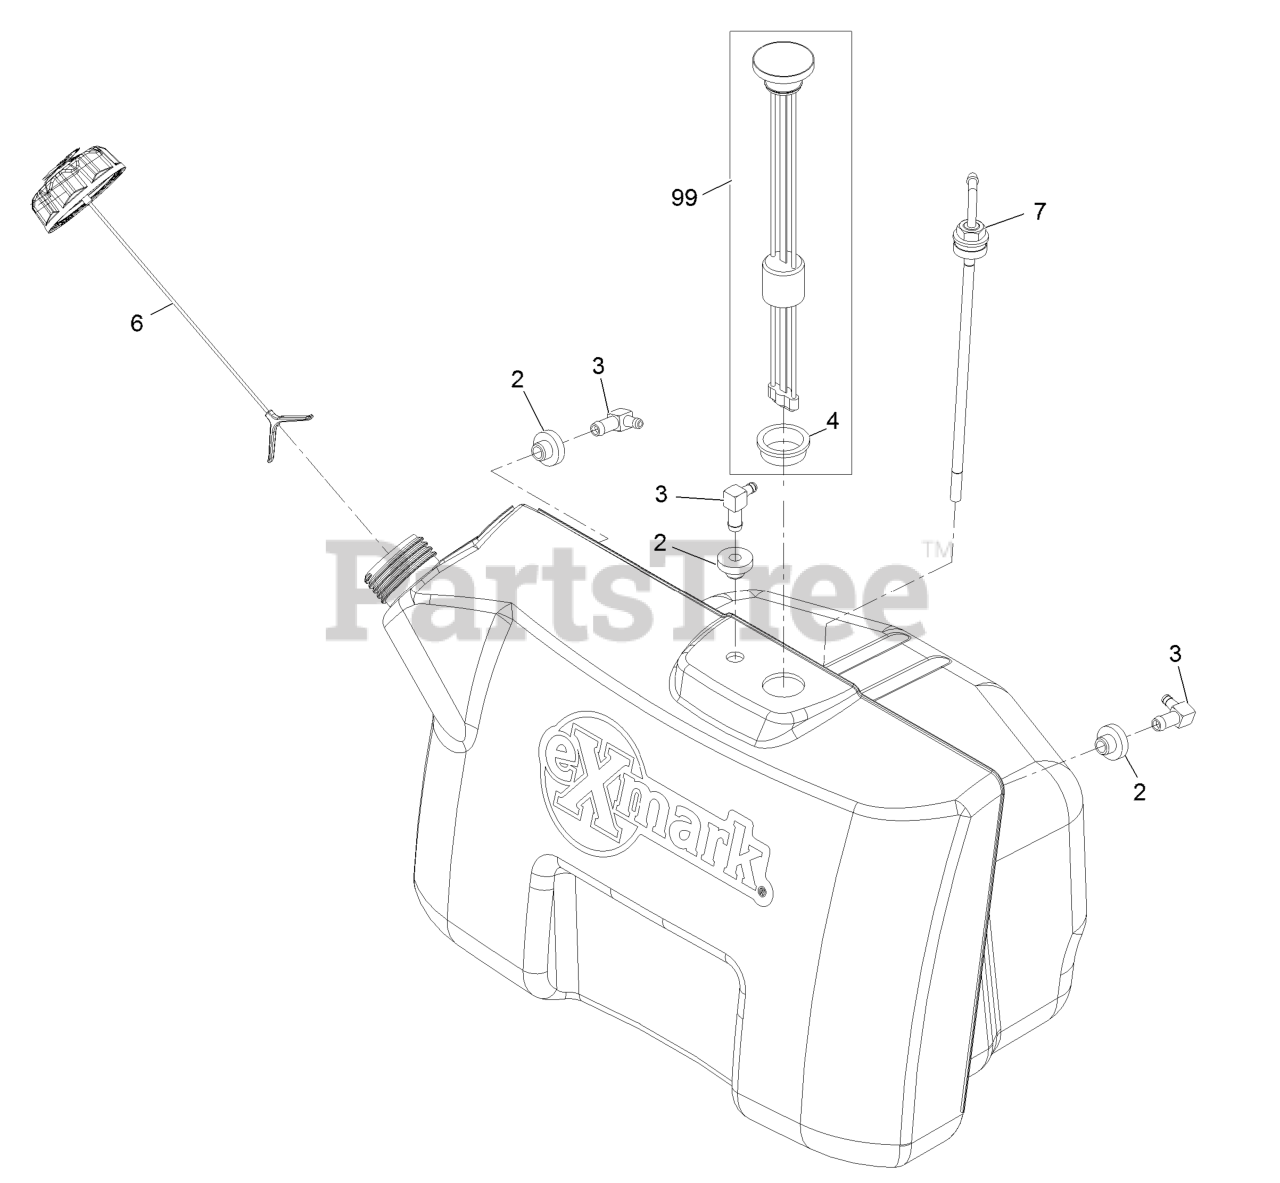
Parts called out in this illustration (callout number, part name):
2	BUSHING
3	ELBOW-90 DEG
4	CONTACT ORDER SERVICES
7	FITTING-FUEL, BULKHEAD
99	KIT, VANTAGE FUEL GAGE RE
